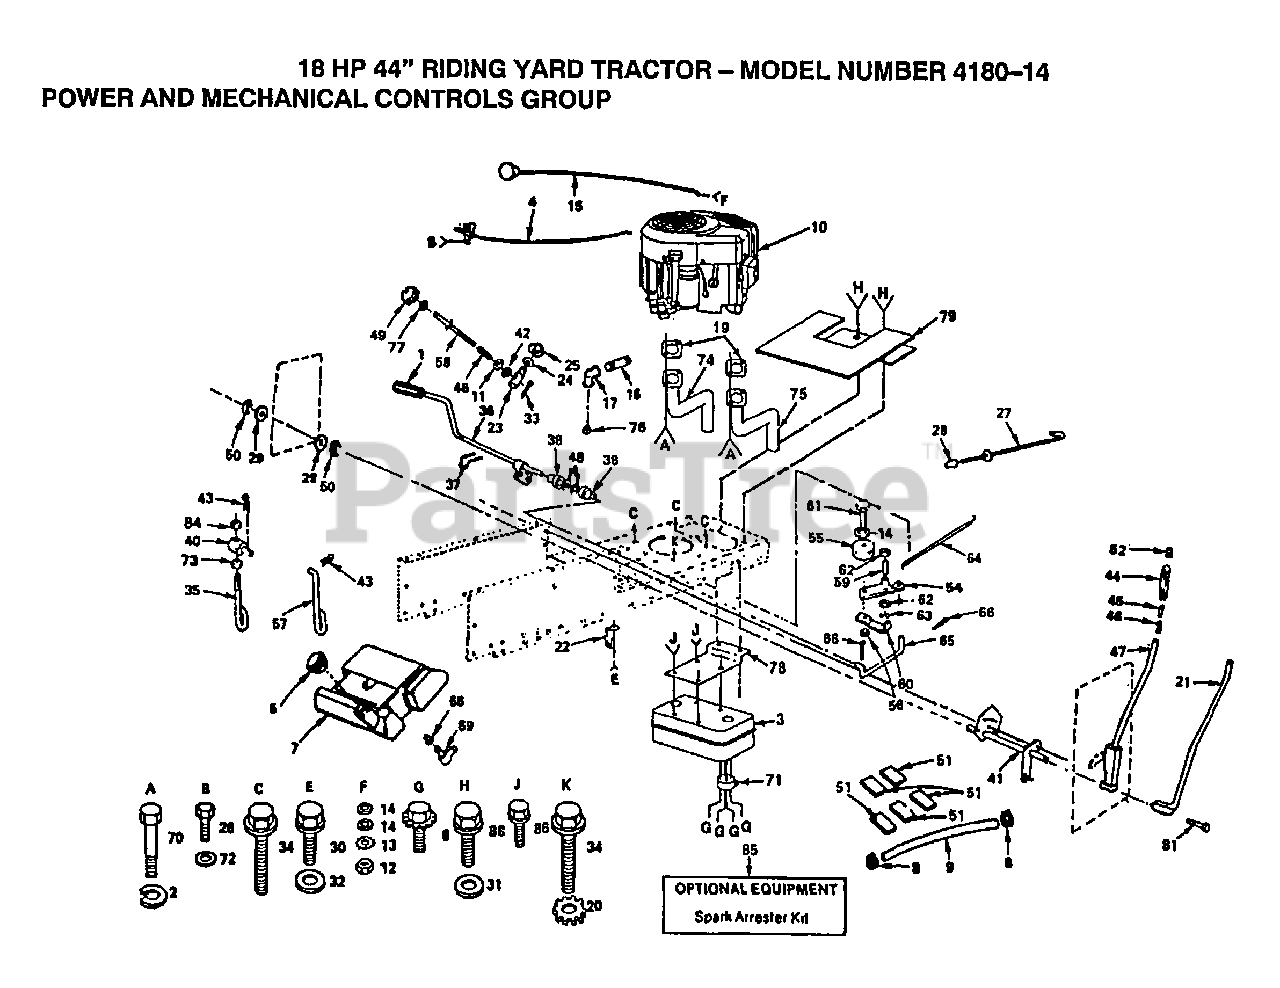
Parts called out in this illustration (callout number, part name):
1	PEDAL COVER T
2	LOCKWASHER
6	SCREW LT
8	HOSE CLAMP
9	FUEL LINE T
11	WASHER
13	LOCKWASHER
14	WASHER
16	PIPE NIPPLE LT
17	ELBOW
20	LOCKWASHER
21	LEVER ROD LT
22	RETAINER BELT
23	TRUNION LT
24	WASHER
25	KLIP RING
26	SCREW
27	ROD BRAKE PARK
28	PLUNGER CAP T
29	WASHER
30	SCREW
31	WASHER
32	WASHER
34	SCREW LT
35	PIVOT PIN T
38	NYLON BEARING
41	SHAFT LIFT LT
42	NUT T
44	GRIP
46	SPRING T
48	WASHER LT
49	HDLE ADJ LIFT
50	E-RING
51	PAD-SPACER LT
54	ARM IDLER
57	LIFT LINK LT
58	ROD LIFT LT
60	RETAIN BELT
62	WASHER LT
63	KLIP RING
64	"SPRING, RETURN LT"
65	"LINK, CLUTCH T"
66	COTTER PIN
68	BUSHING OUTLET T
69	FUEL TANK STEM GT
71	DEFLECTOR.222573
73	NUT
77	NUT
78	BRACKET MUFFLER
81	"BOLT,HEX"
86	SCREW ST
